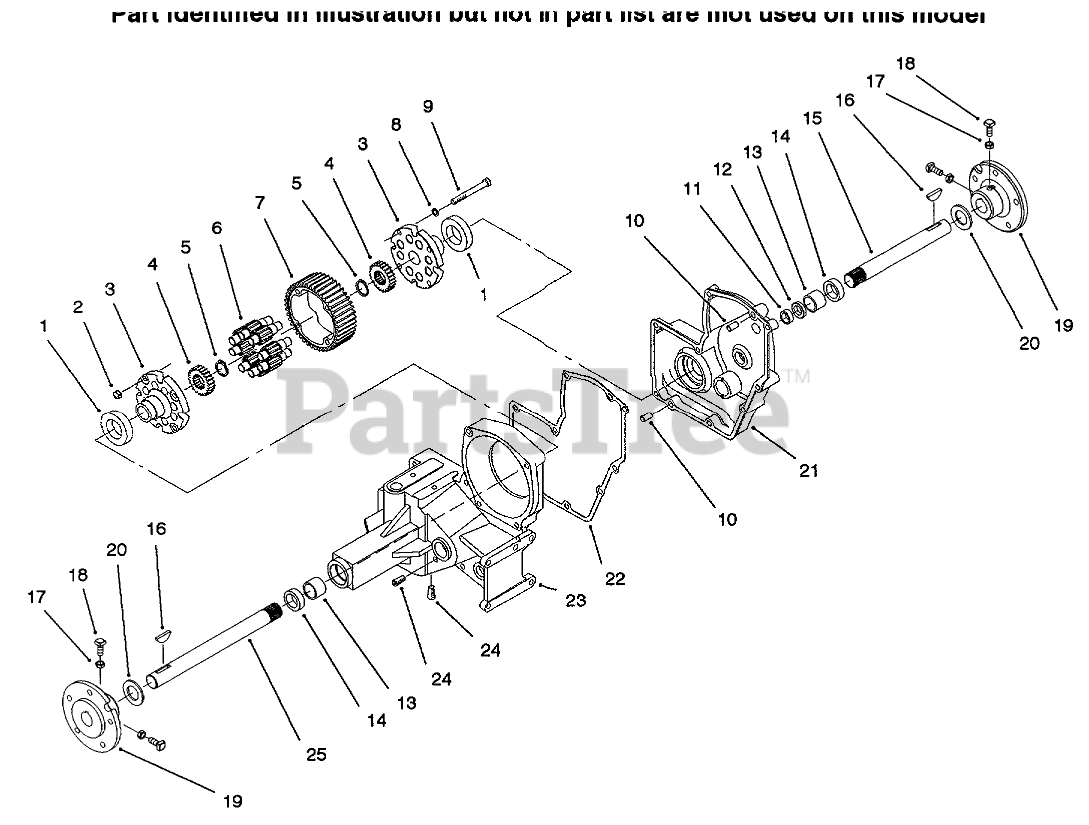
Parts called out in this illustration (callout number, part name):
1	BEARING-BALL
1:1	Plate
1:2	NON SERVICE PART
3	END CAP-DIFFERENTIAL
4	GEAR-AXLE DIFFERENTIAL
5	RING-SNAP
6	GEAR-PINION, 11T
7	GEAR-DIFFERENTIAL RING, 43T
8	WASHER
9	BOLT-HEX
10	PIN-LOCATING
11	NEEDLE BEARING
12	Seal
13	BEARING
14	SEAL-OIL
15	AXLE-REAR LH
16	KEY-WOODRUFF
17	NUT-JAM
18	SCREW-SET, SQH
19	Hub Rear
20	WASHER-THRUST
21	CASE TRANS LH
22	GASKET-TRANSMISSION
25	CASE-TRANS RH
26:1	GEAR 46T
26:2	PINION SHAFT
27	AXLE-REAR RH
